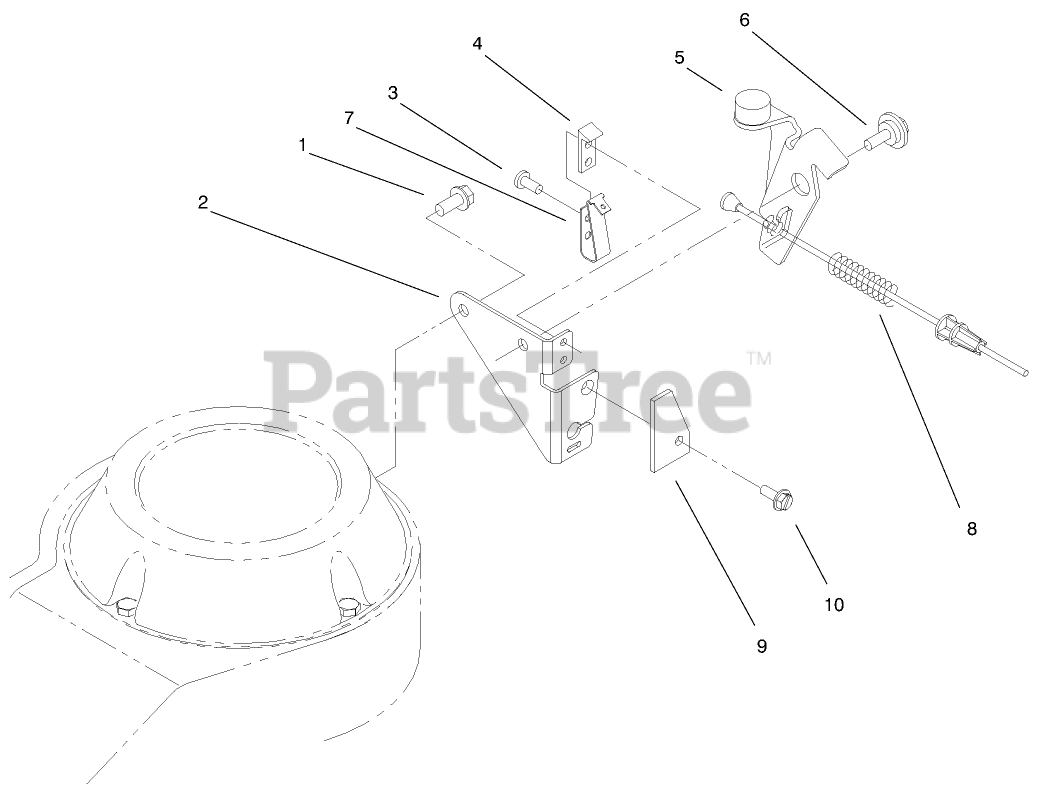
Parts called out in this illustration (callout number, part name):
1	SCREW-HWH
2	PLATE-BRAKE
3	RIVET-PLASTIC
4	STRAP-INSULATING
5	BRAKE PLATE ASM
6	SCREW-SHOULDER
7	STRAP-GROUND
8	SPRING-COMPRESSION
9	STOP-GROUND STRAP
10	SCREW-HWH
